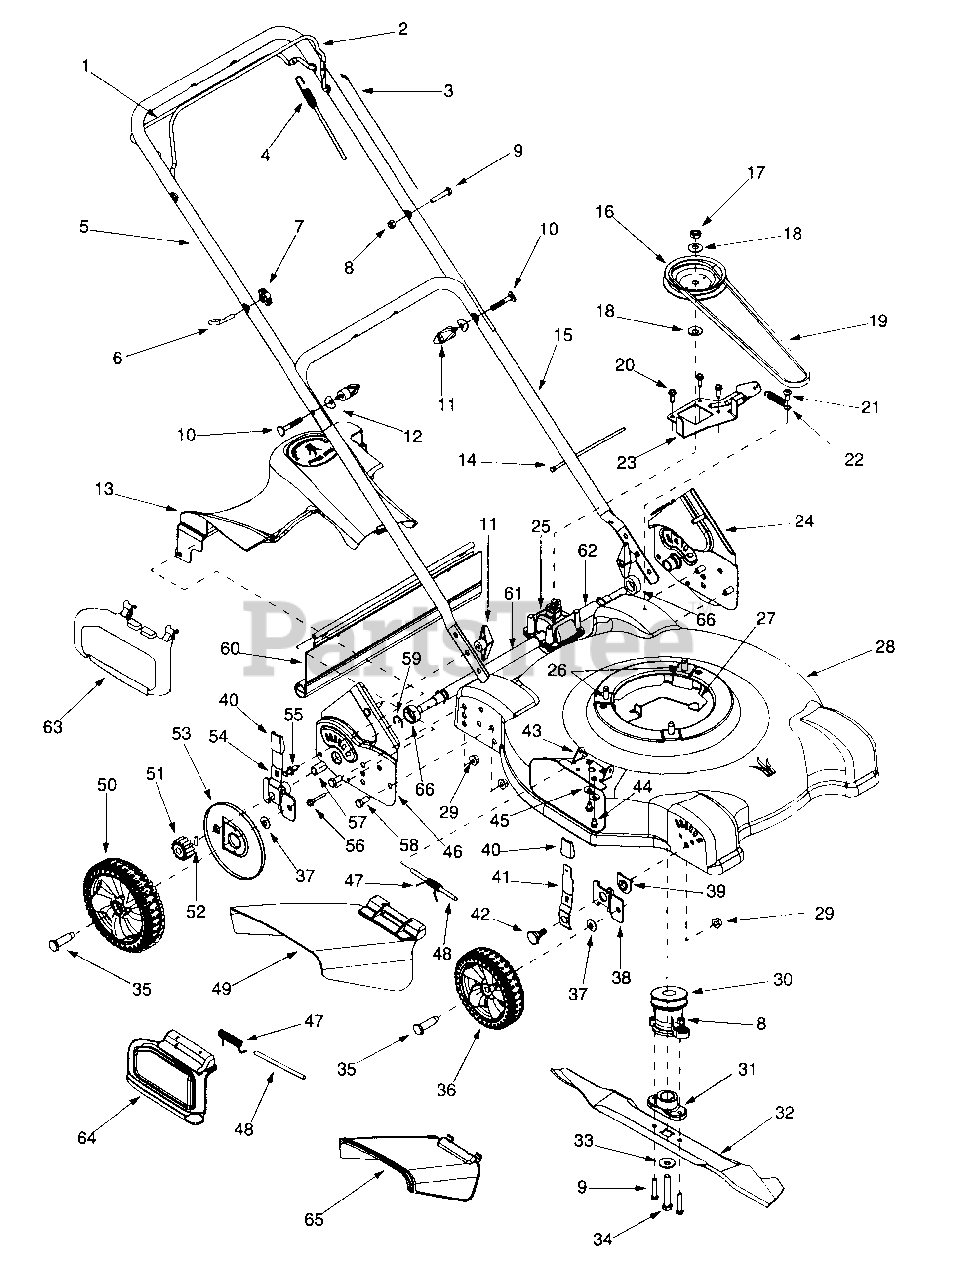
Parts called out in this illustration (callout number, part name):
1	Drive Control Handle
2	Blade Control Handle
3	Blade Control Cable - B&S
4	Drive Control Cable
6	Eye Bolt
7	Wing Nut 1/4-20
8	Hex Lock Nut 1/4-20
9	Hex Cap Screw 1/4-20 x 1.5
10	Carriage Bolt 5/16-18 x 2.0
11	Wing Nut 5/16-18
12	Shoulder Washer .320 ID x .93 OD
13	Transmission Cover
14	Cable Tie
16	Transmission Pulley
17	Jam Nut 7/16-20
18	Bell Washer .45 ID x 1.00 OD
19	V-Belt
20	Hex Washer Screw 1/4-20 x .75
21	Shoulder Screw .375 x.25
22	Extension Spring
23	Transmission Belt Bracket
26	Hex Washer Screw 3/8-16 x 1.0
27	Engine Belt Keeper Bracket
30	Engine Pulley
31	Blade Adapter
32	Blade 22"
33	Bell Washer .396 ID x 1.140 OD
34	Hex Cap Screw 3/8-24 x 2.5
35	Shoulder Screw 3/8-16
36	Front Wheel Comp 7 x 1.8
37	Bell Washer .401 ID x .870 OD
38	Pivot Arm Assembly
39	Height Adjuster Bearing
40	Height Knob
41	Spring Lever
42	Shoulder Screw 3/8-16
43	Chute Hinge
44	Hex Washer Screw 1/4-20 x .50
45	Bell Washer .265 ID x .75 OD
48	Hinge Pin
49	Side Discharge Assembly
50	Rear Wheel Comp 8 x 1.8
51	Spur Gear 147 RH
52	Pin
53	Wheel Cover
54	Spring Lever Assembly - RH
55	Plastic Rivet
56	Screw 1/4-20
57	Sleeve Bearing
58	Hex Cap Screw 3/8-16 x .75
59	Retainer Ring
60	Trail Shield
61	Sleeve Spacer .550 ID x 9.0 OD
62	Sleeve Spacer .550 ID x 2.44 OD
63	Snap Mulching Plug
64	Mulching Baffle
65	Snap Discharge Chute
66	Bearing Spacer
